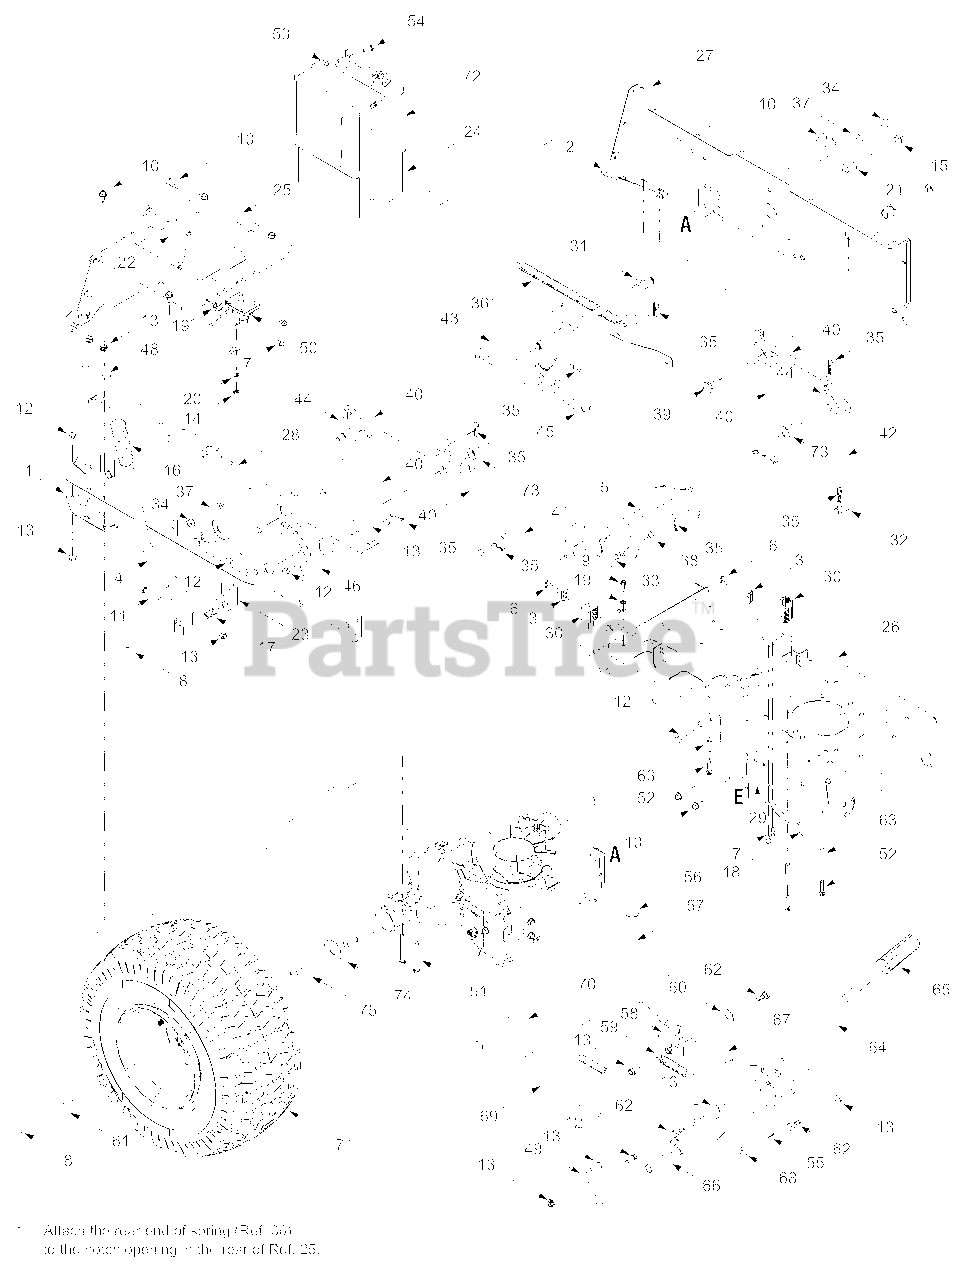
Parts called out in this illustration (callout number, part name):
6	Self-tapping Screw, #10-16 x .5
7	Self-tapping Screw, 1/4-20 x .5
8	Hex Cap Screw, 5/16-24 x .75
9	Self-tapping Screw, 1/4-20 x .75
10	Self-tapping Screw, 5/16-12 x .75
11	Hex Cap Screw, 5/16-18 x 1.75
12	Hex Screw, 5/16-18 x .75
13	Lock Nut, 5/16-18
14	Hex Nut, 1/4-20
15	E-Ring, .625 Dia Shaft
16	Handle Grip
17	Compression Spring, .55 x 1.37
18	Switch Actuator Spring
19	External Lock Washer, 1/4
20	Lock Washer, 1/4
21	Flange Bearing, .632 ID
22	Battery Hold-down Rod
23	Lift Shaft Connector
33	Ferrule, 3/8-24 x .375
34	Flange Lock Nut, 3/8-16
35	Internal Cotter Pin, .080 x 1.56
36	Extension Spring, .730 x 13.0
37	Bell Washer, .389 x 1.12 x .030
38	Flat Washer, .385 x .87 x .060
39	Shoulder Bolt, .625 x .217
40	Deck Hanger Link
41	Deck Disengagement Rod
42	Deck Hanger Link
43	Stabilizer Rod
44	Lift Link
46	Deck Lift Index Bracket
48	Transaxle Mounting Bracket
51	Hex Cap Screw, 5/16-18 x 2.75
52	Self-tapping Screw, 1/4-20 x 1.25
53	Hex Sems Nut, 1/4-20
54	Hex Screw,1/4-20 x .75
55	Cotter Pin, 1.0
56	Ball Knob
57	Brake Lockout Rod
58	Bracket
59	Extension Spring, 4.31
60	Flat Washer, .442 x 1.38 x .060
61	Bell Washer, .34 x .872 x .060
62	Shoulder Screw, .437 x .286
63	Spacer, .260 x .372 x 1.030
66	Spacer, .640 x .76 x 2.63
67	Brake Lockout Bracket
68	Flat Washer, .344 x .750 x .120
69	Brake Rod
70	Extension Spring, 22.16
72	Battery, 190 CCA
73	Spacer, .635 x 1.0 x .696
74	Flat Washer, .755 x 1.92 x .060
75	Plastic Sleeve
